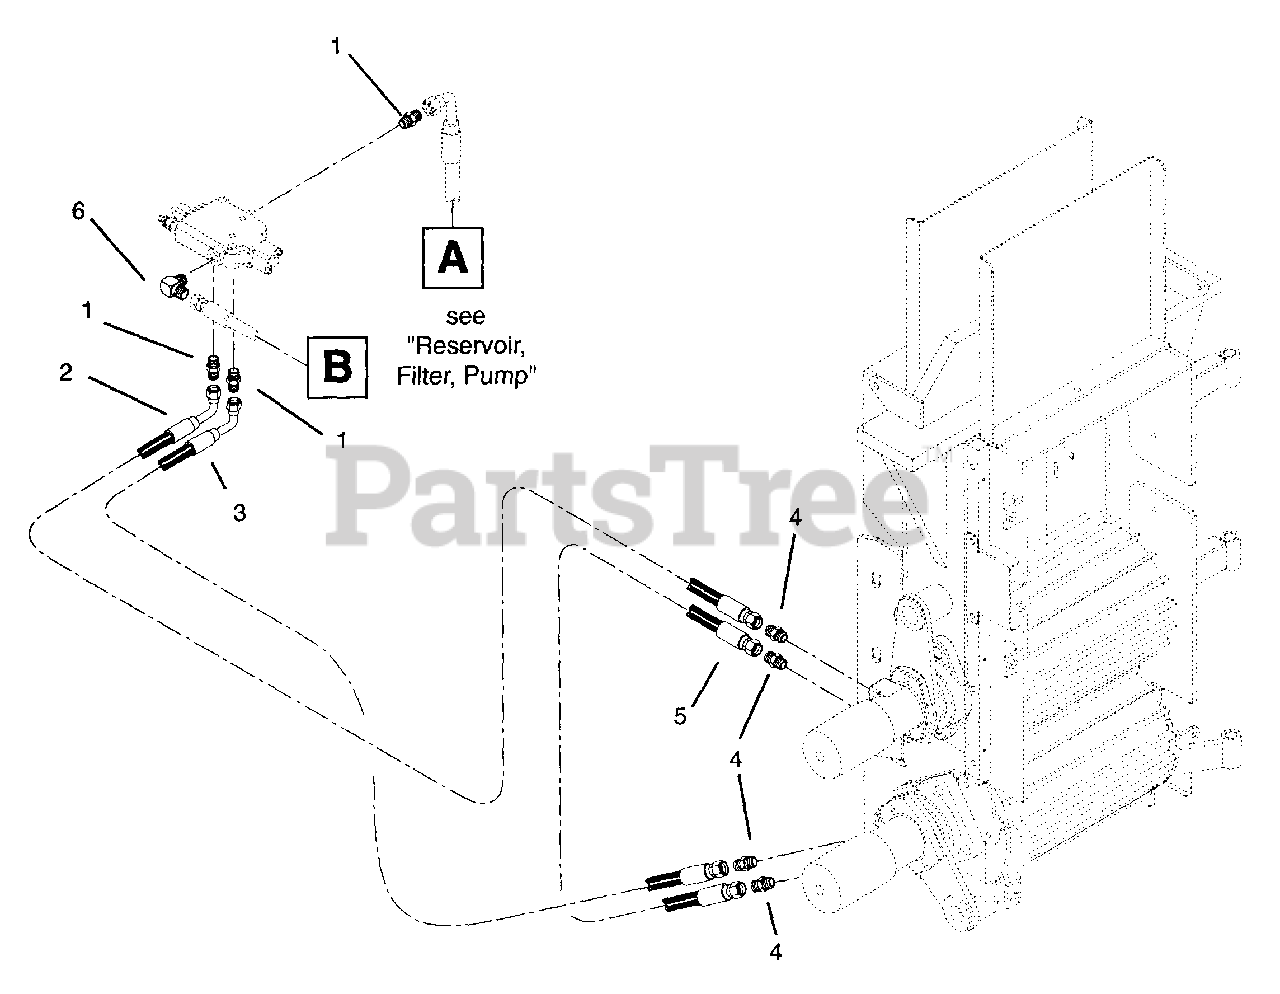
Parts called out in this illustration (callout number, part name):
1	Adapter-Hydraulic Straight 3/4 "O" to 3/4
2	Hose-Hydraulic 45' with Elbow
3	Hose-Hydraulic 30' with Elbow
4	Adapter-Hydraulic Straight 7/8 "O" to 3/4
5	Hose-Hydraulic 40'
6	Adapter-Hydraulic Elbow 3/4 "O" to 3/4
